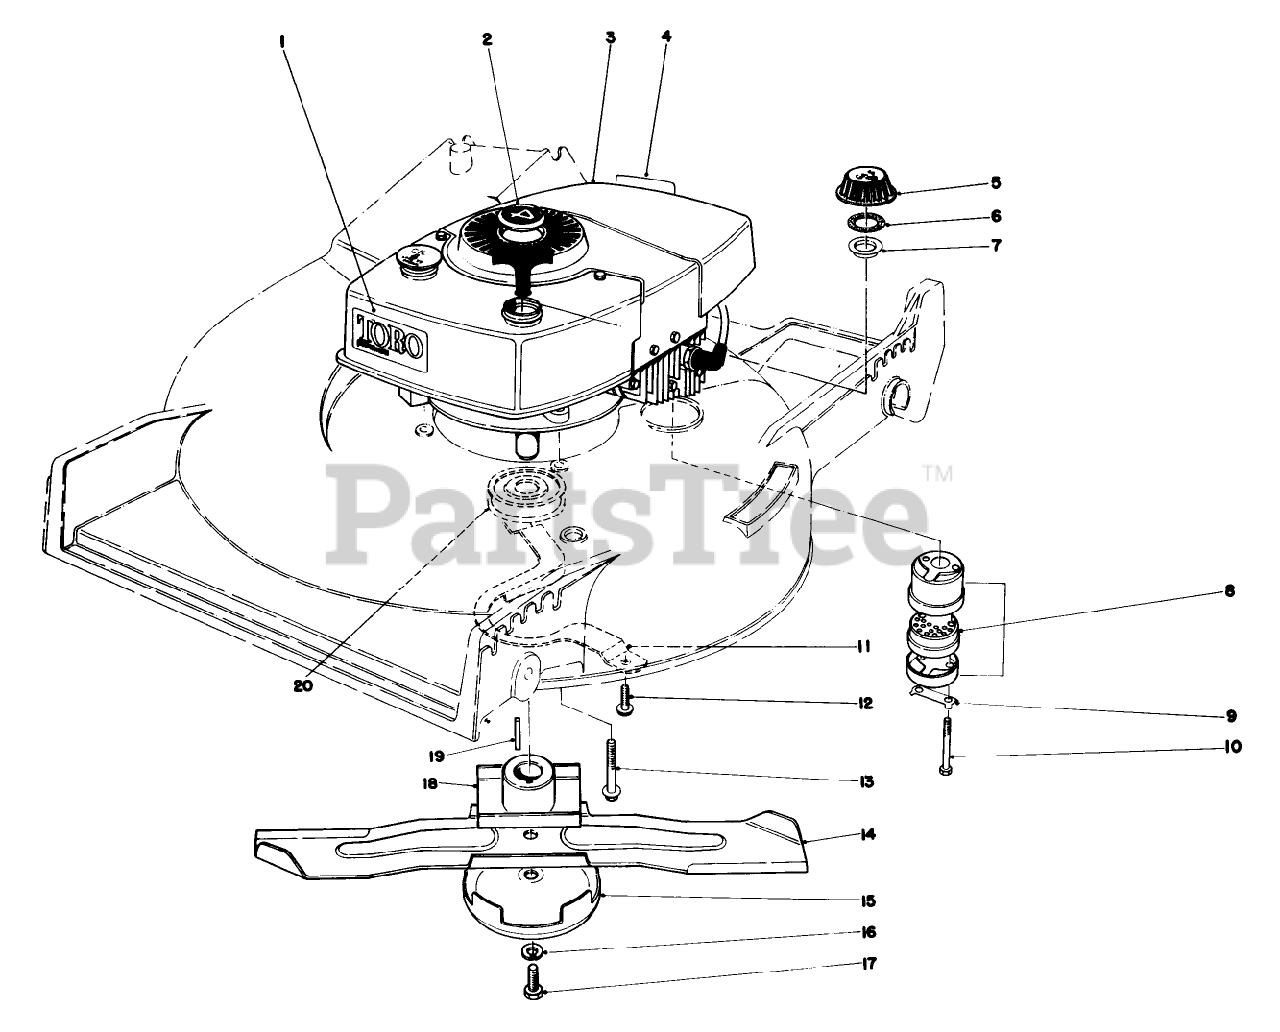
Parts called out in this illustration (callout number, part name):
1	Decal
2	PLUG BUTTON
3	Engine
4	Decal-Maintenan
5	Gas Cap (Incl. Ref. #6 & 7)
6	GASKET
7	GAS CAP BAFFLE
8	Muffler Assy. (Incl. Ref. #9 & 10)
9	CLIP - LOCKING
10	SCREW-HH
11	BELT GUIDE
12	Screw
13	SCREW-HWHTF
14	Blade
15	Anti Scalp Cup
16	WASHER-LOCK
17	BLADE SCREW
18	BLADE RETAINER WA(BLACK)
19	KEY-SQUARE
20	DRIVER PULLEY
